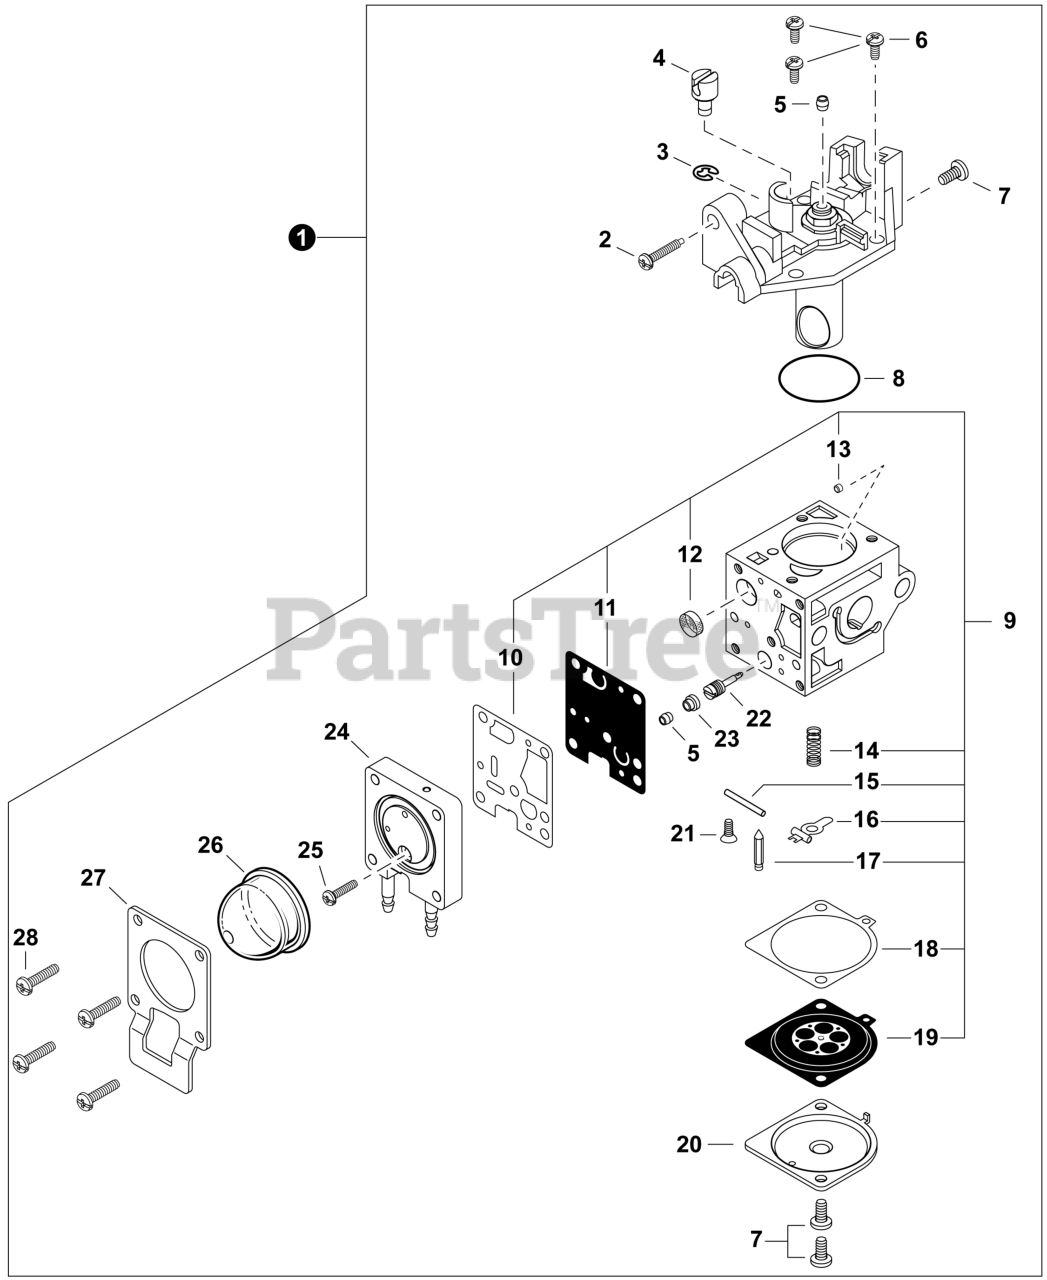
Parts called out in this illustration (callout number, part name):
1	CARBURETOR - GL-3A
2	SCREW, THROTTLE ADJUST
3	E-RING
4	SWIVEL
5	PLUG
6	SCREW
7	SCREW
8	O-RING
9	REPAIR KIT, CARBURETOR
10	GASKET, PUMP
11	DIAPHRAGM, PUMP
12	SCREEN, FUEL INLET
13	GUIDE, ROLLER
14	SPRING, METERING LEVER
15	PIN, METERING LEVER
16	LEVER, METERING
17	VALVE, INLET NEEDLE
18	GASKET, METERING DIAPHRAGM
19	DIAPHRAGM, METERING
20	COVER, METERING DIAPHRAGM
21	SCREW
22	NEEDLE, HIGH SPEED
23	CAP, LIMITER
24	BODY ASSY, PURGE
25	SCREW
26	BULB, PURGE
27	RETAINER, PURGE BULB
28	SCREW
